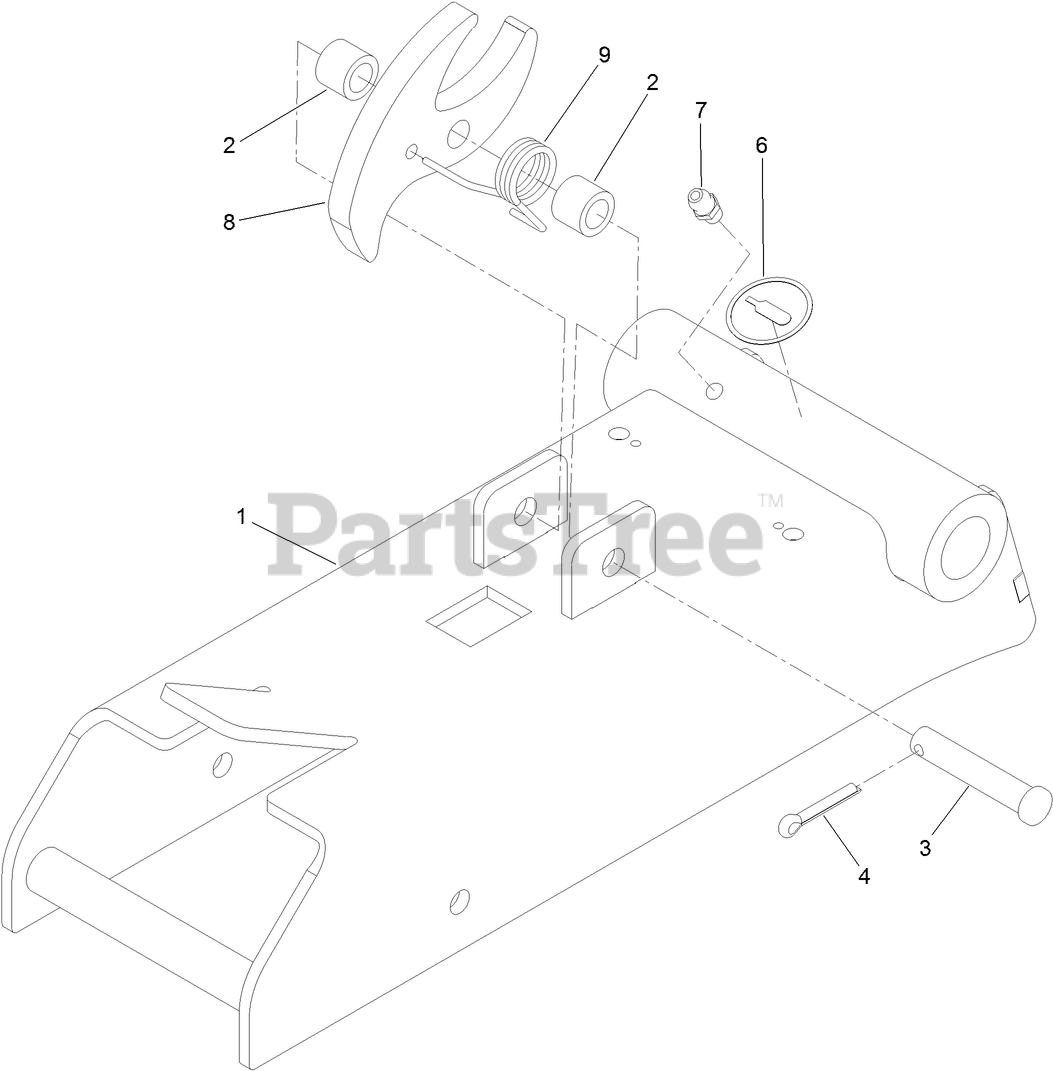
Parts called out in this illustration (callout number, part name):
1	LINKAGE-WRAPPER, WLD
2	SPACER
3	PIN-CLEVIS
4	PIN-COTTER
6	DECAL-GREASE
7	FITTING-GREASE
8	LATCH-PLATFORM
9	SPRING-TORSION, RH
